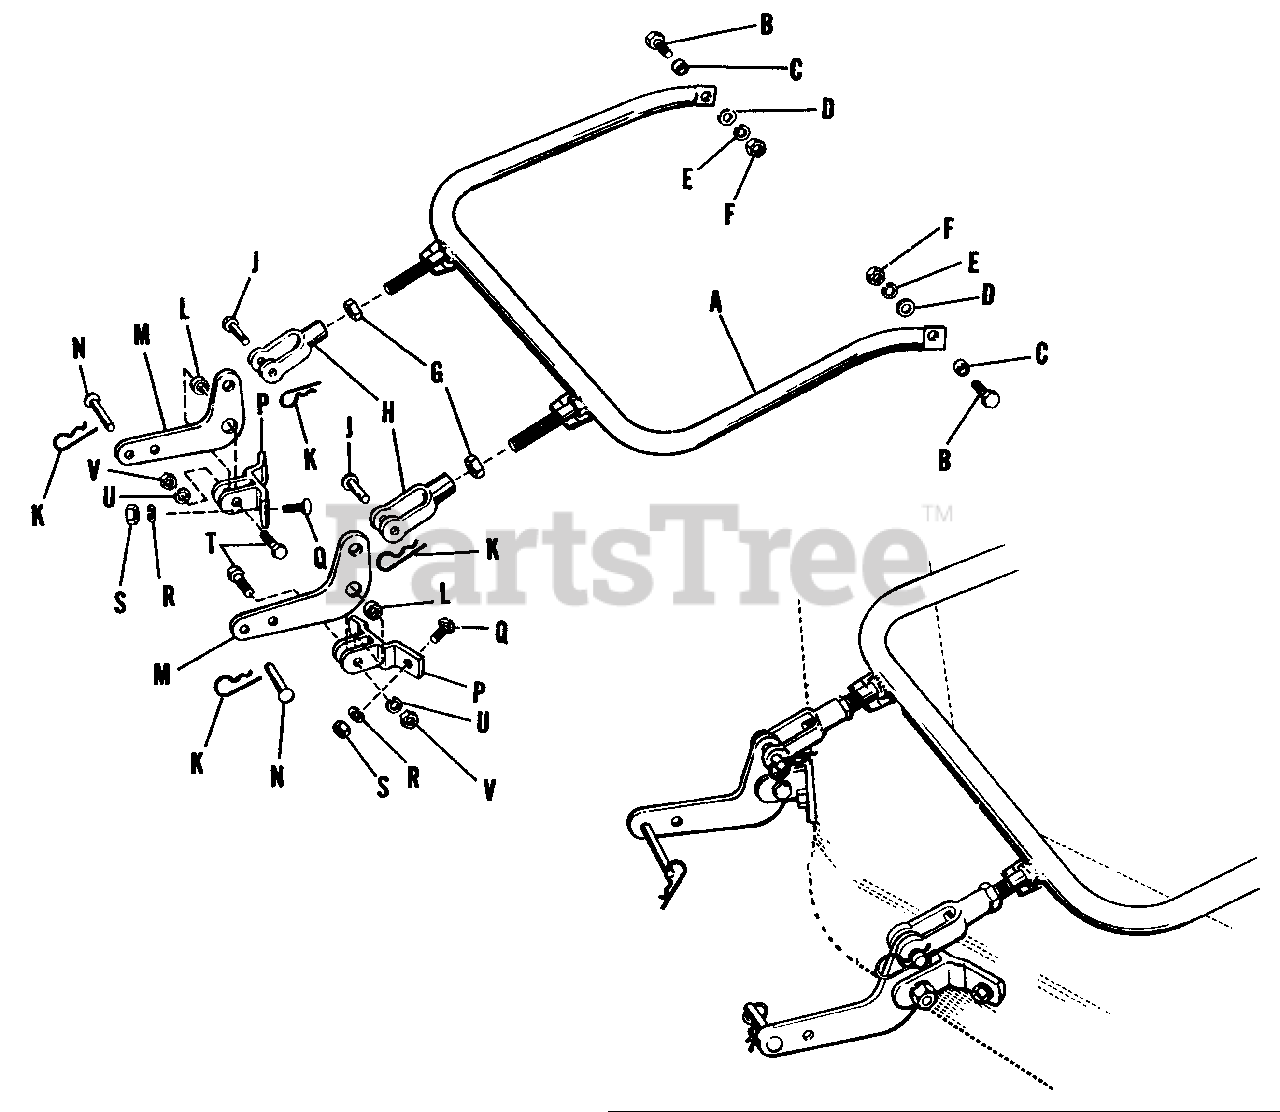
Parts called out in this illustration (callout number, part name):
A	Bail Assembly
B	Capscrew, Hex Hd., 1/2"-13 NC x 1 1/4" lg.
D	Washer, Plain, 1/2"
E	Washer, Lock, 1/2"
F	Nut, Hex, Full, 1/2"-13 NC
G	Nut, Hex, Jam, 1/2"-20 NF
H	Yoke End, Adjusting
K	Clip, Spring
M	Rocker Arm
N	Pin
P	Bracket Assembly, Front
Q	Bolt, Carriage, 3/8"-16 NC x 1"
R	Washer, Lock, 3/8"
S	Nut, Hex, Full, 3/8"-16 NC
T	Capscrew, Hex, 1/2"-13 NC x 1 1/4"
U	Washer, Lock, 1/2"
V	Nut, Hex, Full, 1/2"-13 NC
